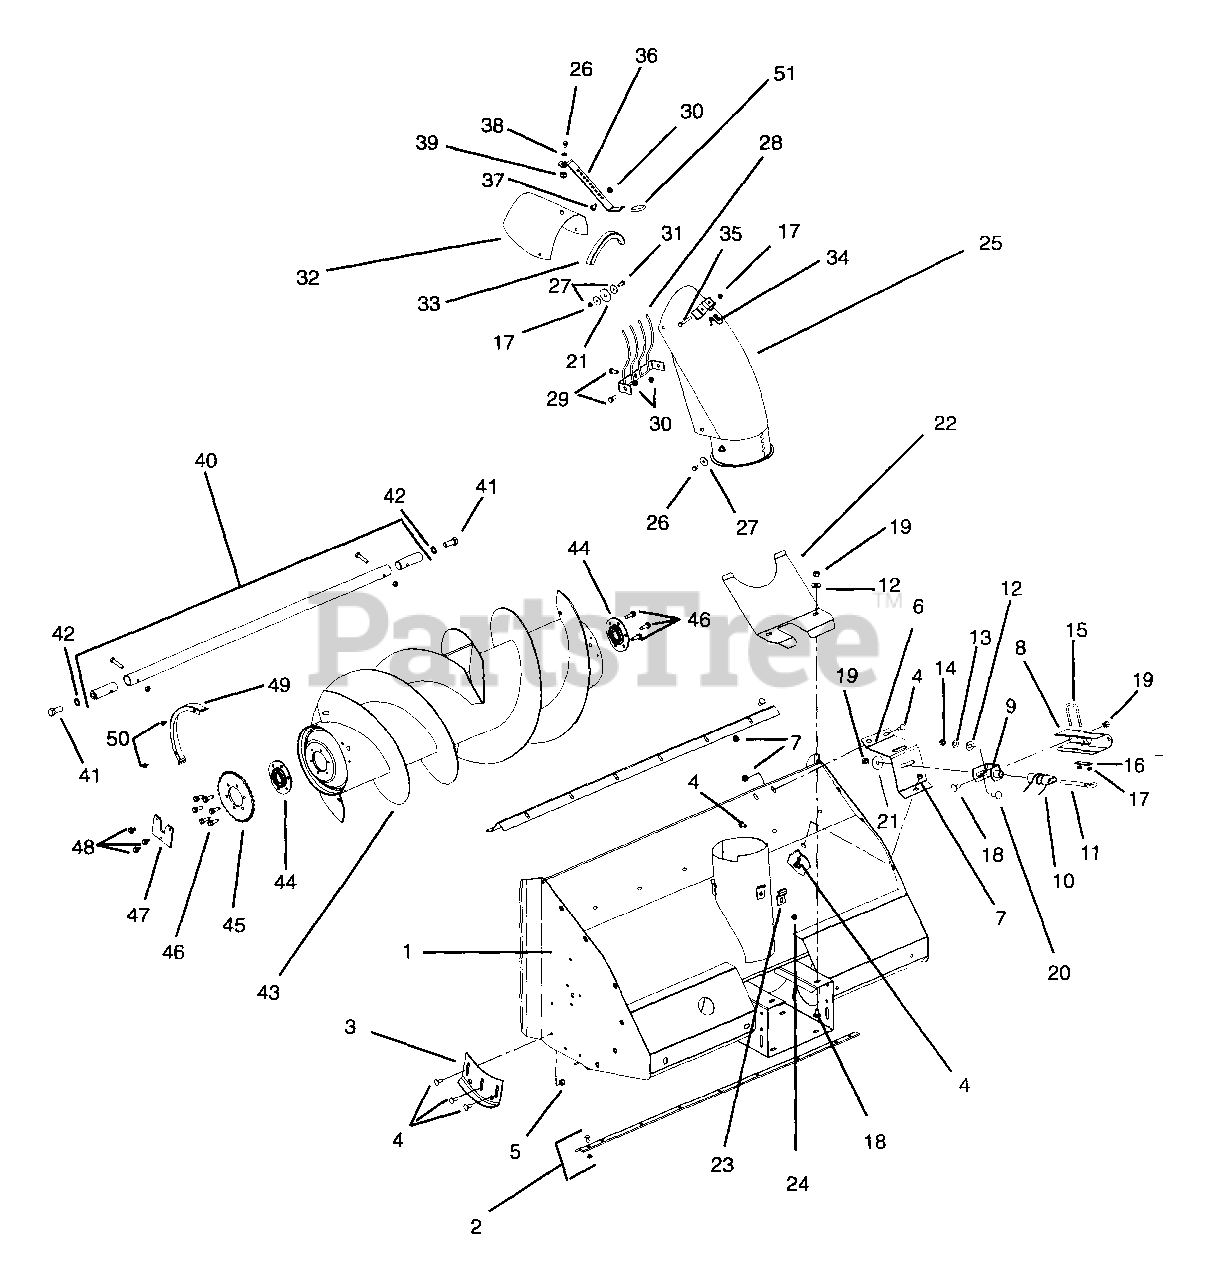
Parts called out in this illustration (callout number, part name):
1	HEADER AND DECAL ASSEMBLY
2	REPAIR KIT 40" SCRAPER BLADE
3	SKID SHOE
4	@BLT-RDHDSQNK .31-18X.75 G5YZ
5	NUT&LOCKWASHER ASSY 5/16-18
6	STACK DRIVE SUPPORT
7	SERRATED FLANGE NUT 5/16-18
8	STACK DRIVE SHROUD
9	BRACKET & TUBE ASSEMBLY
10	CABLE,TUBE,&SLEAVE ASSEMBLY
11	STACK DRIVE EYE BOLT
12	@WSHR-FL-STL.438X1.00X.083 YWZ
13	SPRING WASHER
14	@NUT-LK-CTR .38-16 YWZC
15	LEVEL WIND U BOLT
16	FRICTION STRAP
17	@NUT-LK-CTR .25-20 YWZC
18	@BLT-RDHDSQNK .38-16X.75 G2YWZ
19	NUT & LOCKWASHER
20	@BLT-RDHDSQNK .38-16X1.00 G2YZ
21	BELT ADJUSTMENT BRACKET
22	DRIVE PULLEY GUARD
23	STACK ANCHOR
24	@NUT-LK-CTR .31-18 YWZC
26	@BLT-HEX .25-20X.50 GR5 YWZC
28	CHUTE GUARD
29	@BLT-HEX .31-18X.75 GR5 YWZC
30	@NUT-LK-CTR .31-18 YWZC
31	@BLT-HEX .25-20X.75 GR5 YWZC
32	RUBBER GROMMET
33	TRIM SEAL
34	DEFLECTOR CONTROL SPRING
35	@BLT-HEX .25-20X1.75 GR5 YWZC
36	DEFLECTOR LOCK STRAP
37	BOLT 5/16-18 X 5/8 HEX HEAD
38	FLAT WASHER
39	RUBBER GROMMET
40	AUGER SHAFT ASSEMBLY
41	@BLT-HEX .50-13X1.25 GR5 YWZC
42	SHAKEPROOF WASHER 1/2
43	AUGER ASSEMBLY 40"
44	BEARING AND FLANGETTE ASSY.
45	AUGER SPROKET 35 TOOTH
46	@SCR-TAP .31-18X1.00 HWH TR YZ
47	AUGER MOUNTING PLATE
48	SELF TAPPING SCREW 5/16-18
49	CHAIN GUARD
50	SELF TAPPING SCREW
51	RUBBER HANDLE GRIP
